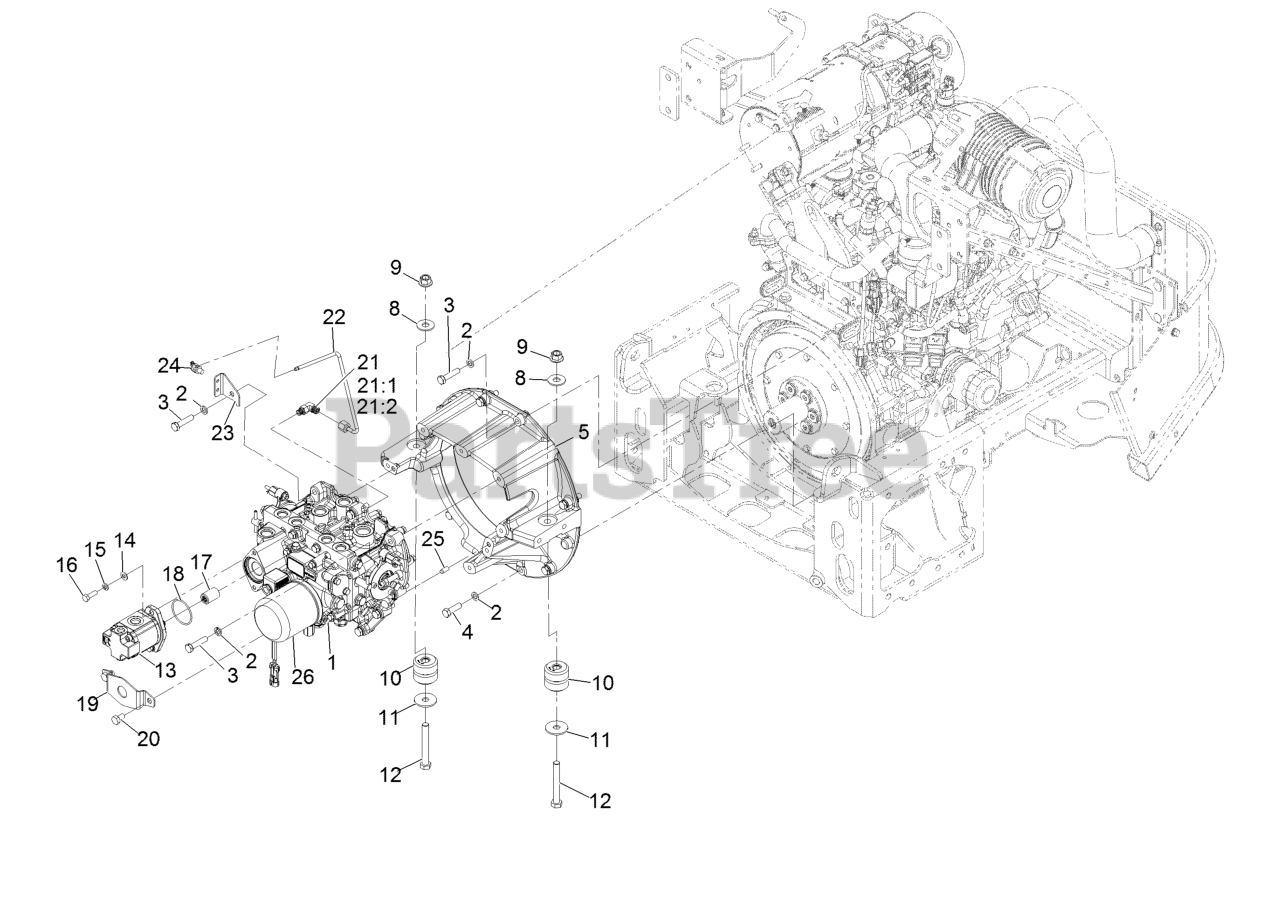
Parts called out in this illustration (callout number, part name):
1	Transmisson ASM
2	Washer-Lock
3	Screw-HH
4	Screw-HH M10-1.5 X 25Mm
5	Housing-Flywheel
8	Washer
9	Nut-Lock 1/2-13
10	Mount-Isolator
12	Screw-HH
13	HYD Gear Pump ASM
14	Washer-5/16 SAE
15	Washer-Lock 5/16
16	Screw-HH M8-1.25 X 25Mm
17	Coupler-Spline
19	Shield-Seal
20	Screw-HH
21	Fitting-Elbow, 90
21:1	O-Ring
21:2	O-Ring
22	Tube ASM
23	Support-Tube
24	Clip-Tie
25	Pin-Dowel
26	Filter-Oil, HYD
